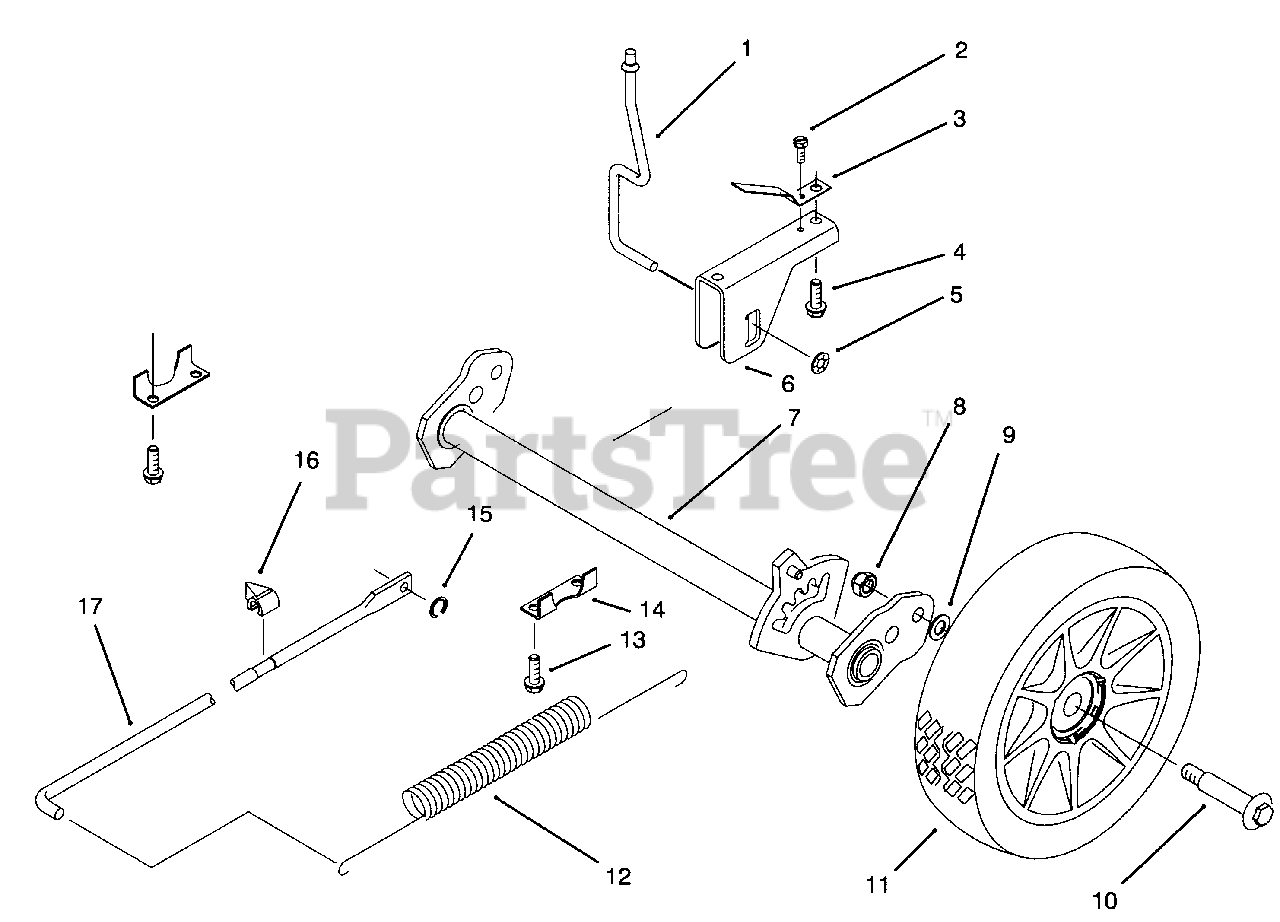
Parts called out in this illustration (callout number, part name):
1	Rod-Trigger
2	Screw-Tapping
3	Spring-Trigger Retainer
6	Saddle-H.O.C.
7	Arm-Pivot
8	Nut-Lock
10	Bolt-Shoulder
11	Wheel & Tire Assembly
12	Spring-Counterbalance
13	Screw-Tapping
14	Plate-Securing Rear
15	Ring-Grip
16	Indicator-H.O.C.
17	Rod-Link
